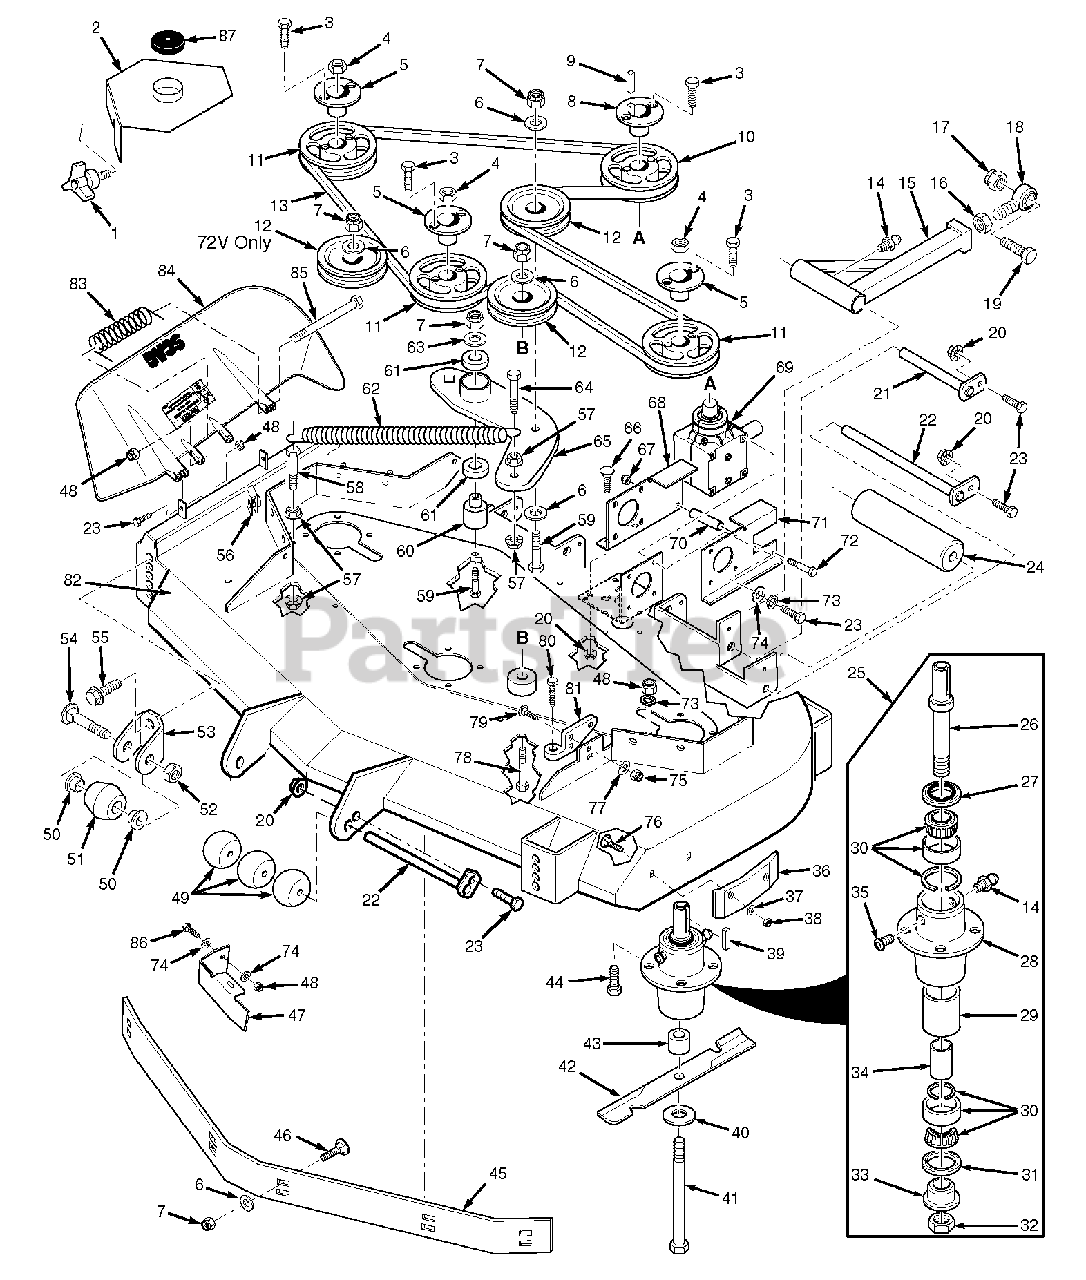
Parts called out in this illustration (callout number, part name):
1	Wing Nut, 3/8-16
2	Belt Cover
2	Belt Cover RH
2	Belt Cover LH
3	Bolt, Hex Head 1/4-20 x 1" Grd 8
4	Nut, 5/8-11 UNC
5	Tapered Hub, 1-1/8" Bore
6	Flatwasher, 3/8" (.391 x .938 x .105)
7	Nut, Hex Elastic Stop 3/8-16
8	Tapered Hub, 1" Bore
9	Key, 1/4 x 1/4 x 1-1/4"
10	Pulley, 6.75 O.D.
10	Pulley, 6.95 O.D.
11	Pulley, 5.75 O.D.
11	Pulley, 6.75 O.D.
12	Pulley, Idler
13	Belt, Cutter Deck Drive
14	Grease Fitting
15	Pusharm
16	Nut, Hex Head 5/8-18 UNF
17	Nut, Hex Elastic Stop 5/8-11
18	Rod End, 5/8" Male RH Thread
19	Bolt, Hex Head 5/8-11 x 4-1/2"
20	Nut, Hex Serrated Flange 5/16-18
21	Push Arm Shaft
22	Roller Shaft
23	Bolt, Hex Head 5/16-18 x 1-3/4"
24	Wheel, Anti-Scalp
25	Spindle Assembly
26	Spindle Shaft
27	Seal, Top
28	Spindle Housing
29	Spacer, Outside
30	Bearing Assembly
31	Seal, Bottom
32	Nut, Special 1-1/16-18
33	Spindle Bushing, Bottom
34	Spacer, Inside
35	Relief Fitting, Tapered Spindle
36	Wear Pad
37	Flatwasher, 5/16"
38	Nut, Center Lock 5/16-18
39	Key, 1/4 x 1/4 x 2"
40	Flatwasher, 5/8" Hardened
41	Bolt, Hex Head 5/8-11 x 9-1/2"
42	Cutter Blade, 21"
42	Cutter Blade, 24.5"
43	Spacer, Spindle Bottom
44	Bolt, Hex Head 5/16-18 x 1-3/4"
45	Baffle, Custom Cut 61V
45	Baffle, Custom Cut 72V
46	Bolt, Carriage 3/8-16 x 1"
47	Discharge Baffle 61V
47	Discharge Baffle 72V
48	Nut, Hex Elastic Stop 5/16-18 Grd 8
49	Wheel, Anti-Scalp
50	Bushing, .376 I.D. Oilite
51	Anti-Scalp Wheel
52	Locknut, 3/8-16 Center Lock
53	Anti-Scalp Wheel Bracket
54	Bolt, Carriage 3/8-16 x 4"
55	Bolt, Hex Serrated Flange 3/8-16 x 1"
56	U-Nut, 3/8-16
57	Nut, Hex Serrated Flange 3/8-16
58	Bolt, Hex Head 3/8-16 x 1-1/2"
59	Bolt, Hex Head 3/8-16 x 3"
60	Pivot, Idler - Short
61	Bearings, Ball
62	Spring, Cutter Deck
63	Flatwasher,3/8-.39 x .938 x .105 HD
64	Bolt, Hex Head 3/8-16 x 1-1/2" Grd 8
65	Idler Arm, Cutter Deck
66	Bolt, Carriage 5/16-18 x 3/4"
67	Nut, Elastic Stop 5/16-18
68	Mounting Plate, RH Gearbox
69	Gearbox Assembly, Deck Drive
70	Spacer, Gearbox Mount
71	Mounting Plate, LH Gearbox
72	Bolt, Hex Head 5/16-18 x 4-3/4"
73	Lockwasher, 5/16"
74	Flatwasher, 5/16" (.375 x .875 x .083)
75	Nut, Elastic Stop 7/16-14
76	Bolt, Carraige 5/16-18 x 3/4"
77	Flatwasher, 7/16-.500 x 1.25 x .083
78	Bolt, Hex Head 3/8-16 x 3-1/4"
79	Bolt, Carriage 7/16-14 x 1-1/4"
80	Bolt, Deck Adjust
81	Lever Assy, Deck Level
82	Cutter Deck 61 V w/Decals
82	Cutter Deck 72 V w/Decals
83	Spring, Discharge Chute
84	Discharge Chute 61V
84	Discharge Chute 72V
85	Bolt, Hex Head 5/16-18 x 4-1/2"
86	Bolt, Hex Head 5/16-18 x 1"
87	Cap, Spindle
